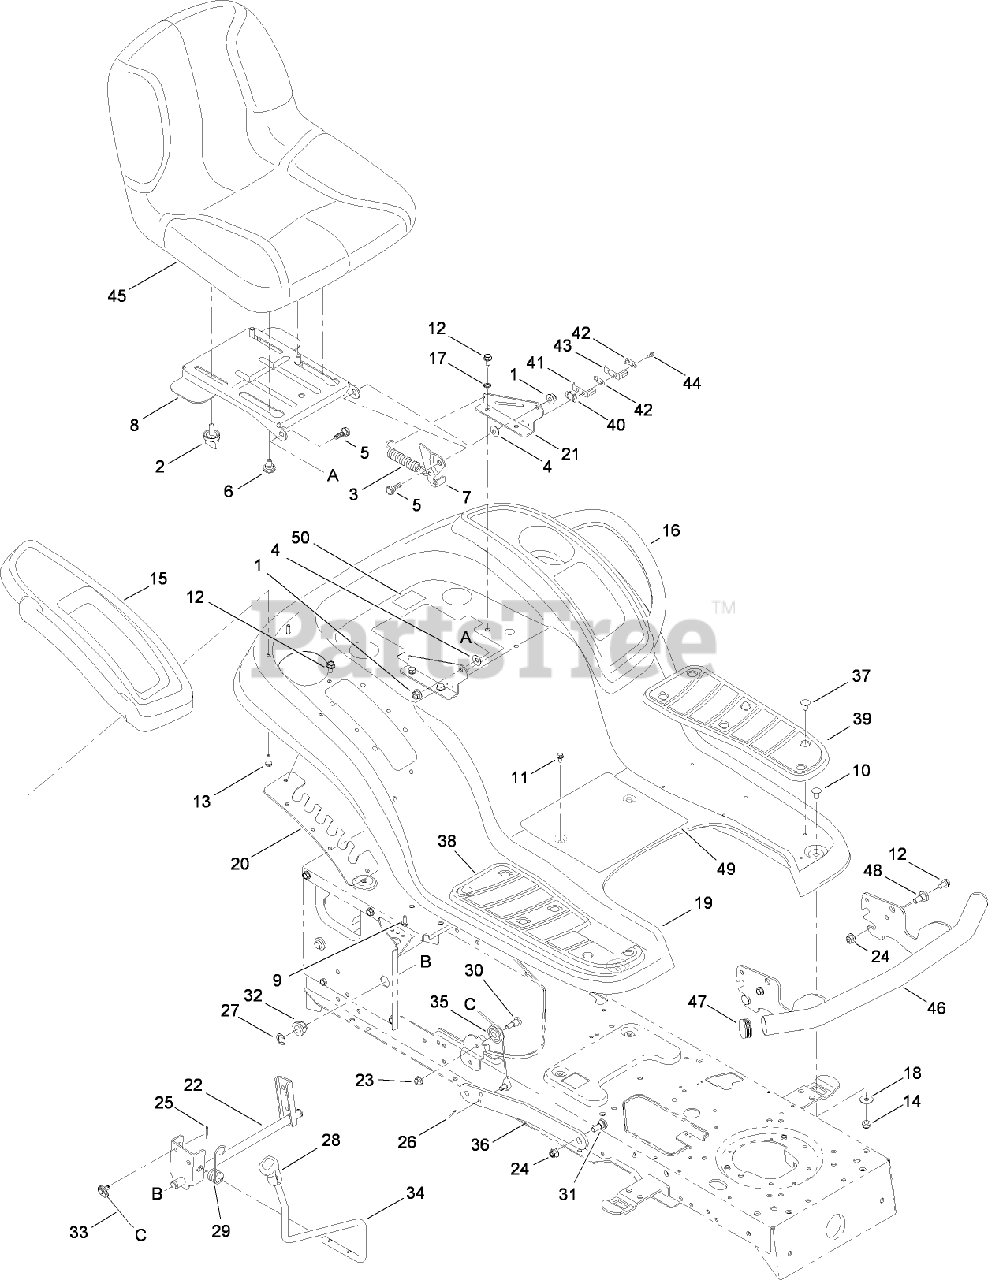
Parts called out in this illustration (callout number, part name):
1	NUT-LOCK, FLANGE
3	SPRING-EXTENSION
4	WASHER-BELL
5	BOLT-SHOULDER
6	BOLT-SHOULDER
7	BRACKET-LIFT, LH
8	BRACKET-PIVOT, SEAT
10	BOLT-CARR
11	SCREW-HWHTF
12	SCREW-TAP
13	SCREW-TAP
14	NUT-LOCK, FLANGE
15	COVER-FENDER, RH
16	COVER-FENDER, LH (W/CUPHOLDER)
17	WASHER-LOCK, EXTERNAL
18	WASHER-FLAT
19	FENDER
20	BRACKET-ADJUSTING, LIFT
21	BRACKET-MOUNT, SEAT
22	LIFT SHAFT ASM
23	NUT-LOCK, FLANGE
24	NUT-LOCK, FLANGE
25	PIN-COTTER
26	PIN-COTTER
27	RING-E
28	GRIP-HANDLE
29	SPRING-TORSION
30	BOLT-SHOULDER
31	BOLT-SHOULDER
32	BEARING-FLANGE
33	CABLE-LIFT
34	HANDLE-LIFT
35	PULLEY-ROLLER
37	CLIP-RATCHET, FASTENER
38	PAD-FOOT, RH
39	PAD-FOOT, LH
40	PLATE-BOSS, INSULATOR
41	SWITCH-SPRING, INNER
42	PLATE-INSULATOR
43	SWITCH-SPRING
44	SCREW-HWHTF
45	SEAT-MEDIUM BACK
46	BUMPER ASM
47	CAP-HUB
48	BOLT-SHOULDER
49	DECAL-INSTRUCTIONS, OPERATOR
50	DECAL-SERVICE
